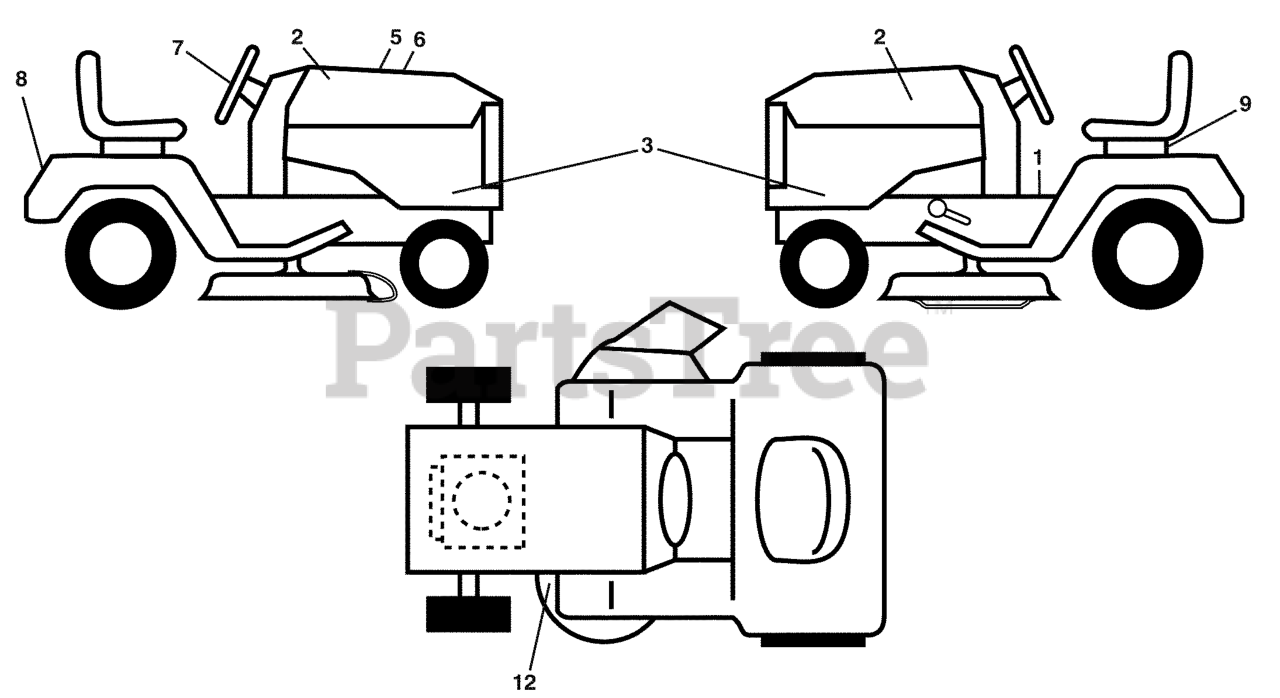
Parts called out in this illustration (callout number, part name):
1	DECAL.WARN.START.INSTRUCTIONS
2	DECAL.HOOD.LOGO.HUSQVARNA
3	DECAL, HOOD PANEL SD
5	DECAL HOOD CUST. RESP.
6	DECAL.RPL.KH.SV600.TLW.46"
7	DECAL.WHEEL.STRG.LGN.H
8	DECAL.FENDER
9	DECAL BTRY SYMBOLS
12	DECAL V BELT SCHEMATIC
